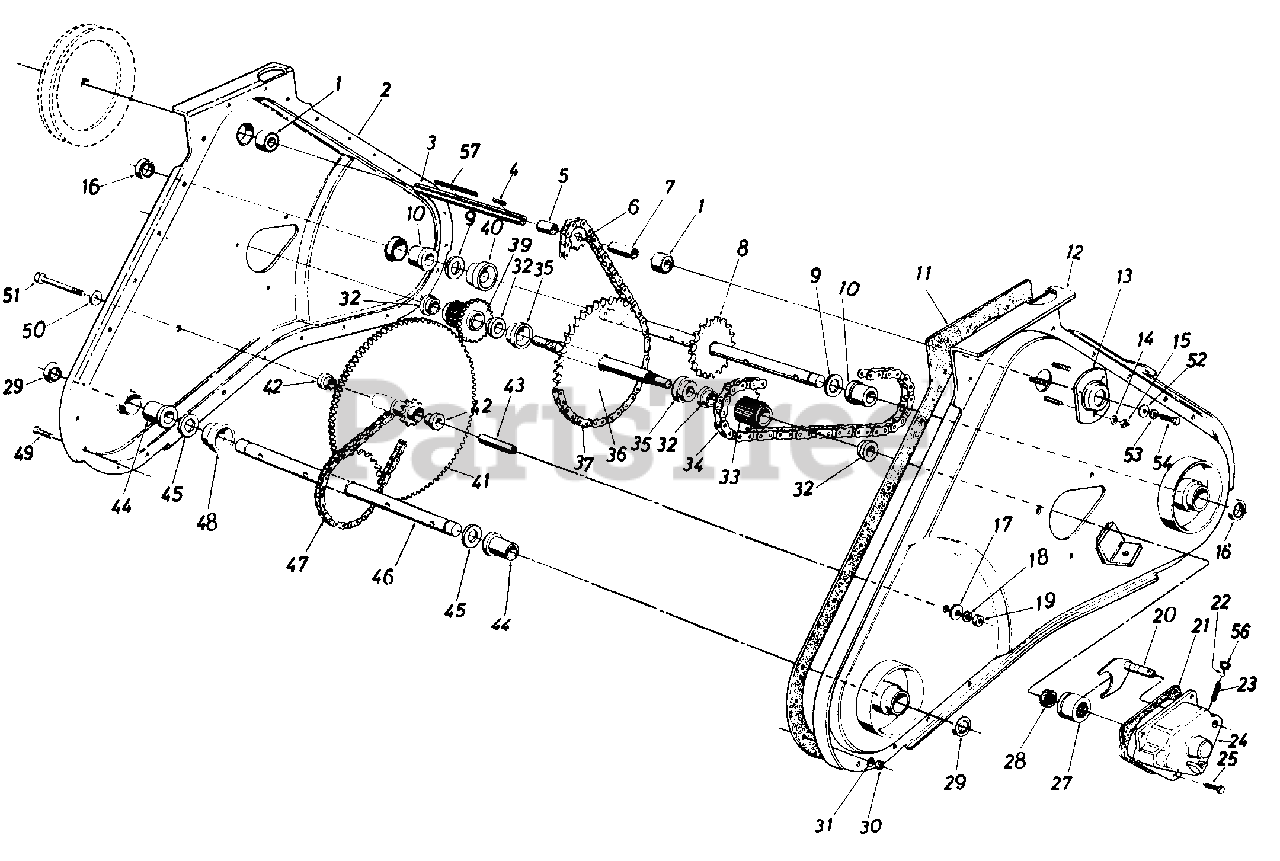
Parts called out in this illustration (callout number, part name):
1	Ball Bearing .62" I.D. x 1.38" O.D. x .44
2	Chain Case R.H. Half
3	Input Shaft .62" Dia.
4	Sq. Key 3/16" x 3/16" x .75" Lg.
5	Spacer .637" I.D. x .781' O.D. x .85" Lg.
6	Sprocket 9 Tooth x .62" Shaft
7	Spacer .637" I.D. x .781' O.D. x 1.44' Lg.
8	Tine Shaft Ass'y.
9	Fl-Wash. 1.28" I.D. x 1.62' O.D.
10	Flange Bearing 1.25" I.D.
11	Gasket-Housing
12	Chain Case L.H. Half
13	Bearing Housing 1-3/8" O.D.
14	L-Wash. 1/4" I.D.*
15	Hex Nut 1/4-28 Thd.
16	Seal 1.25" 1 .D.
17	Belleville Wash .
18	L-Wash. 3/8" I.D.
19	Hex Cent. L-Nut 3/8-24 Thd.
20	Shift Yoke Ass'y.-L.H.
21	Gasket-Shift Housing
22	Ball Detent .250 Dia.
23	Compression Spring
24	Shift Housing-L.H.
25	Hex Tap-Tite 5/16-18 x .75" Lg.
27	Clutch Dog
28	Clutch Dog Driver
29	Seal 1.0" I.D. x 1.38"0.D.
30	Hex Nut 1/4-28 Thd.
31	L-Wash. 1/4" I.D.
32	Flange Brg. 1.00" I.D.
33	Sprocket Brg. Sleeve Ass'y.
34	#50 Chain-5/8" Pitch x 50 Links-Endless
35	Stepped Spacer 1.0" I.D. x 1.75" O.D.
36	Clutch Shaft Ass'y.
37	#420 Chain 1/2" Pitch x 58 Links-Endless
39	Gear Bearing-Sleeve Ass'y.
40	Spacer 1.25" I.D. x 2.0" O.D. x .68" Lg.
41	Sprocket and Gear Ass'y.
42	Flange Brg. .628" I.D. x .753" O.D.
43	Hub Sleeve .38" I.D. x .625" O.D.
44	Flange Brg. 1.00" I.D. x 1.188' O.D.
45	Fl-Wash. 1.0" I.D. x 1.62" O.D.
46	Axle Shaft Ass'y.
47	#420 Chain 1/2" Pitch 46 Links-Endless
48	Spacer 1.0" I.D. x 2.0" O.D.
49	Hex Bolt 1/4-28 x .62" Lg.
50	Belleville Wash.
51	Hex Bolt 3/8-24 x 2.75" Lg.
52	Fl-Wash. 5/16" I.D.
53	L-Wash. 5/16" I.D.
54	Hex L-Bolt 5/16-24 x .75" Lg.
56	Cap Plug .250" Dia.
57	Sq. Key 3/16" x 2.0" Lg.
